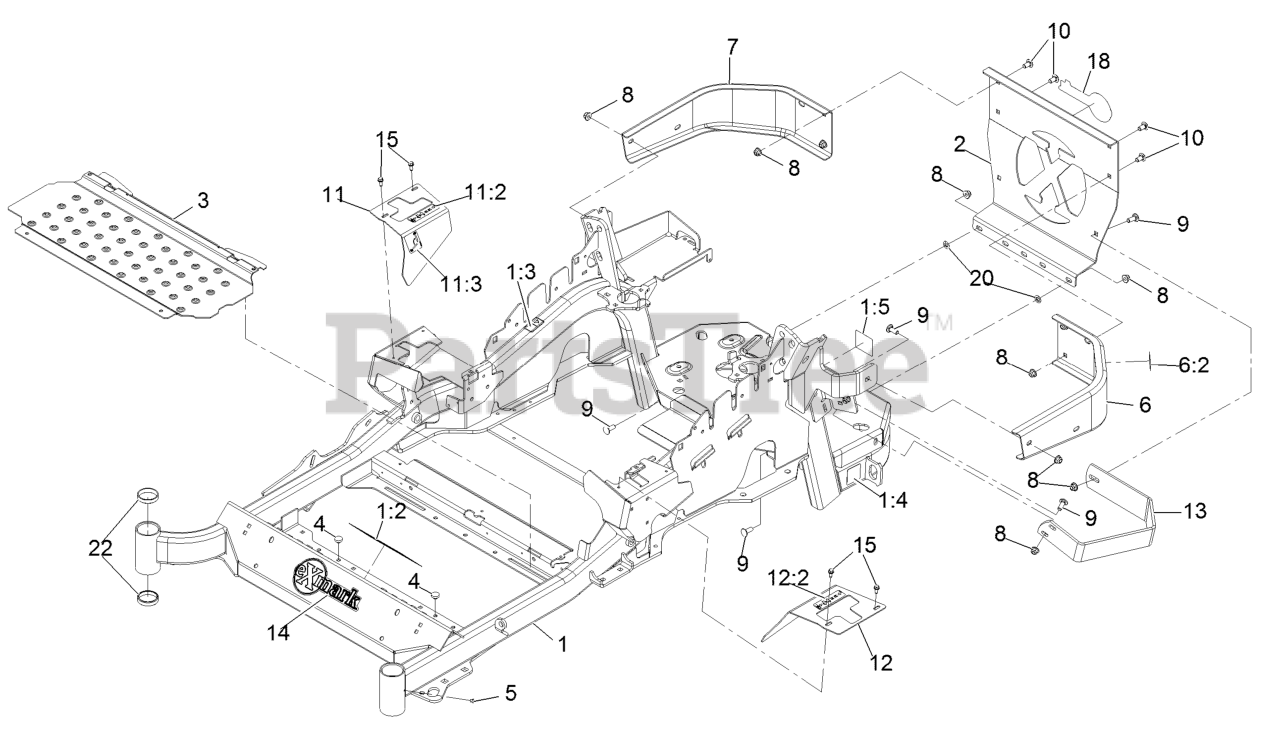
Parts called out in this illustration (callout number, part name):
1	Mainframe ASM
1:2	Decal-Danger
1:3	Decal-Warning
1:4	Decal-Hazard, Pinched Finger
1:5	Decal-Spark Arrester
2	Plate,Rear Guard
6	LH Bumper ASM
6:2	Decal-Warning
7	Bumper-RH
8	Nut-Nyloc 3/8-16 Flg
9	Bolt-Carriage 3/8-16 X 1
10	Bolt-Carriage 3/8-16 X 3/4
11	RH Motion Control Cover ASM
11:2	Decal-Control, Motion
11:3	Decal-Park Brake, CE
12	LH Motion Control Cover ASM
12:2	Decal-Control, Motion
13	Guard-Muffler
14	Decal-Exmark
15	Screw-HWH 1/4-20 X .62
18	Decal-Exmark Logo
20	Nut-Push 3/8-16
22	Cup-Bearing Tapered Roller
